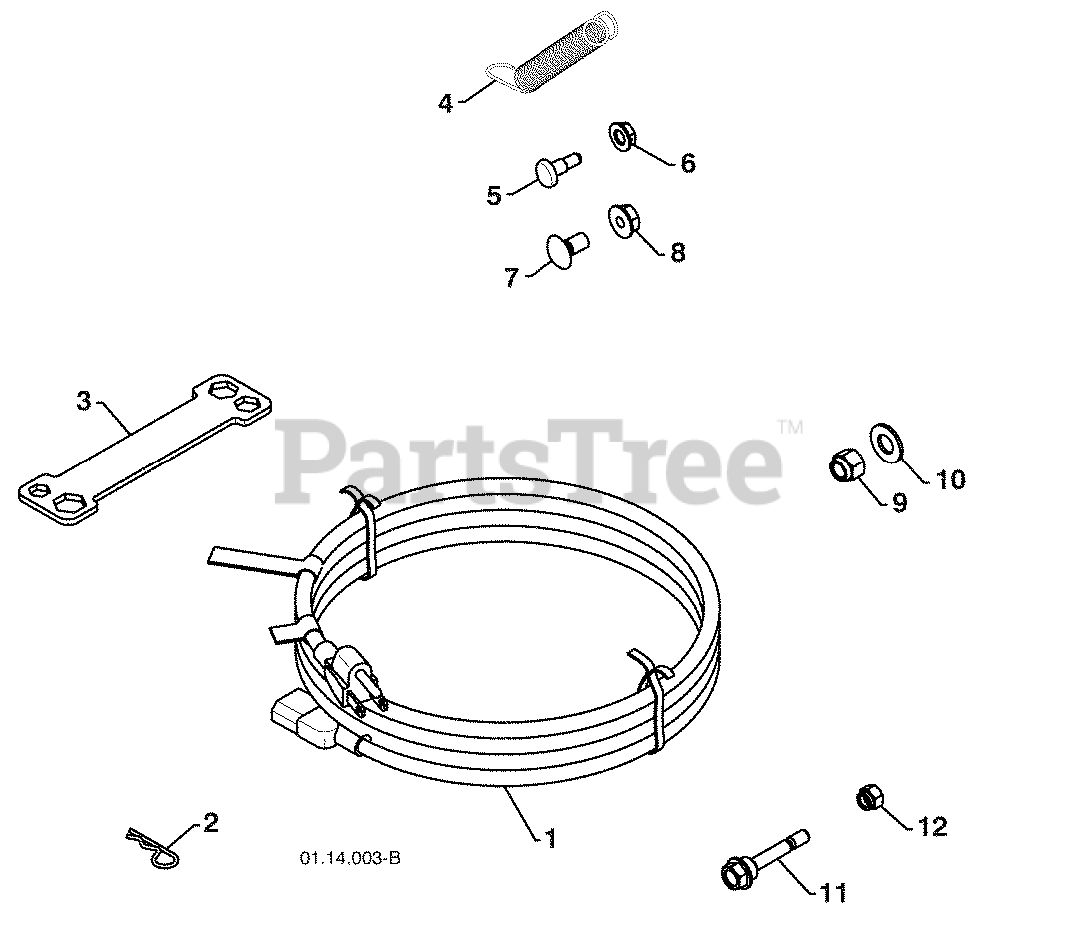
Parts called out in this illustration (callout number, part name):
1	CORD.ELECTRIC.10FT.120V.SNOW
2	SPRING RETAINER
3	RP WRENCH, SNOWTHROWER
4	SPRING.DEFLECTOR.REM.CHUTE
5	BOLT, SHOULDER
6	WASHER, NYLON FRICTION
7	NUT.HEX.FLANGE.1/4
8	BOLT
9	NUT.LOCK.5/16-18
10	NUT
11	BOLT, SHEAR
12	LOCKNUT.NYLOC.1/4-20
